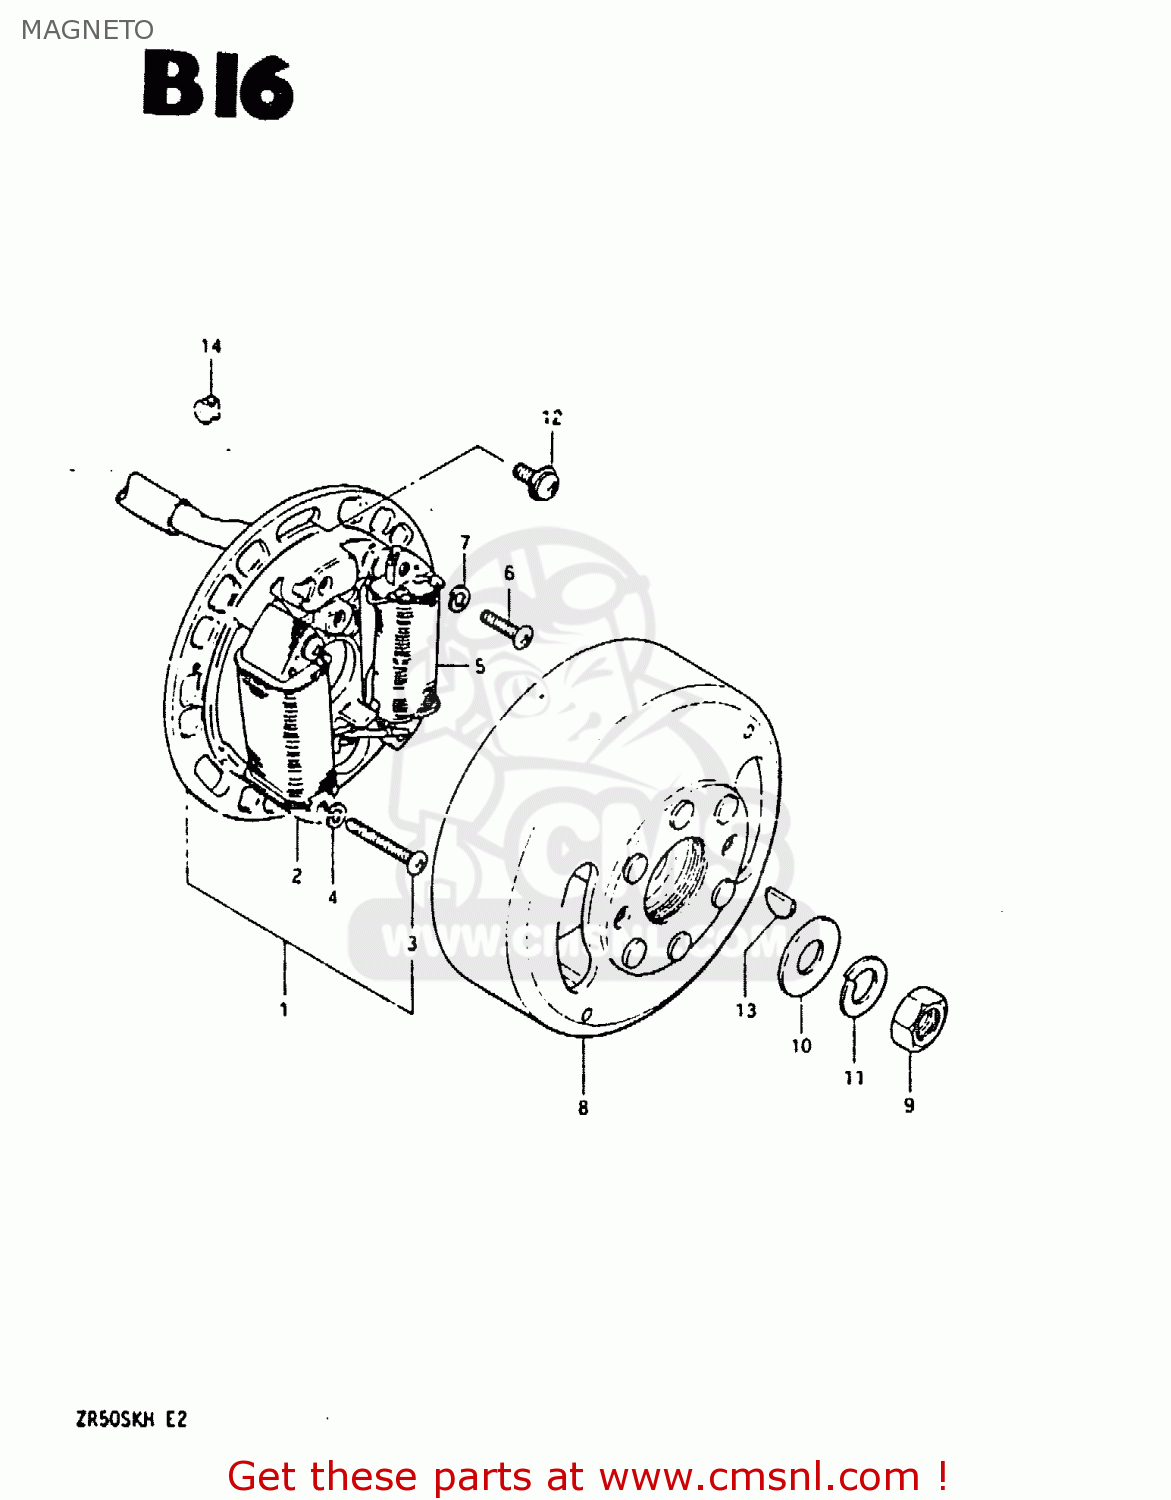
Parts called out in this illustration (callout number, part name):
1	STATOR ASSY
2	COIL,LIGHTING
3	SCREW (4X30)
4	WASHER,LOCK 4M
5	COIL,PRIMARY
6	SCREW
7	WASHER,LOCK 4M
8	ROTOR ASSY
9	NUT (10MM)
10	WASHER
11	WASHER,LOCK,10
12	SCREW
13	KEY
14	GROMMET,NEUTRAL LEAD WIRE
